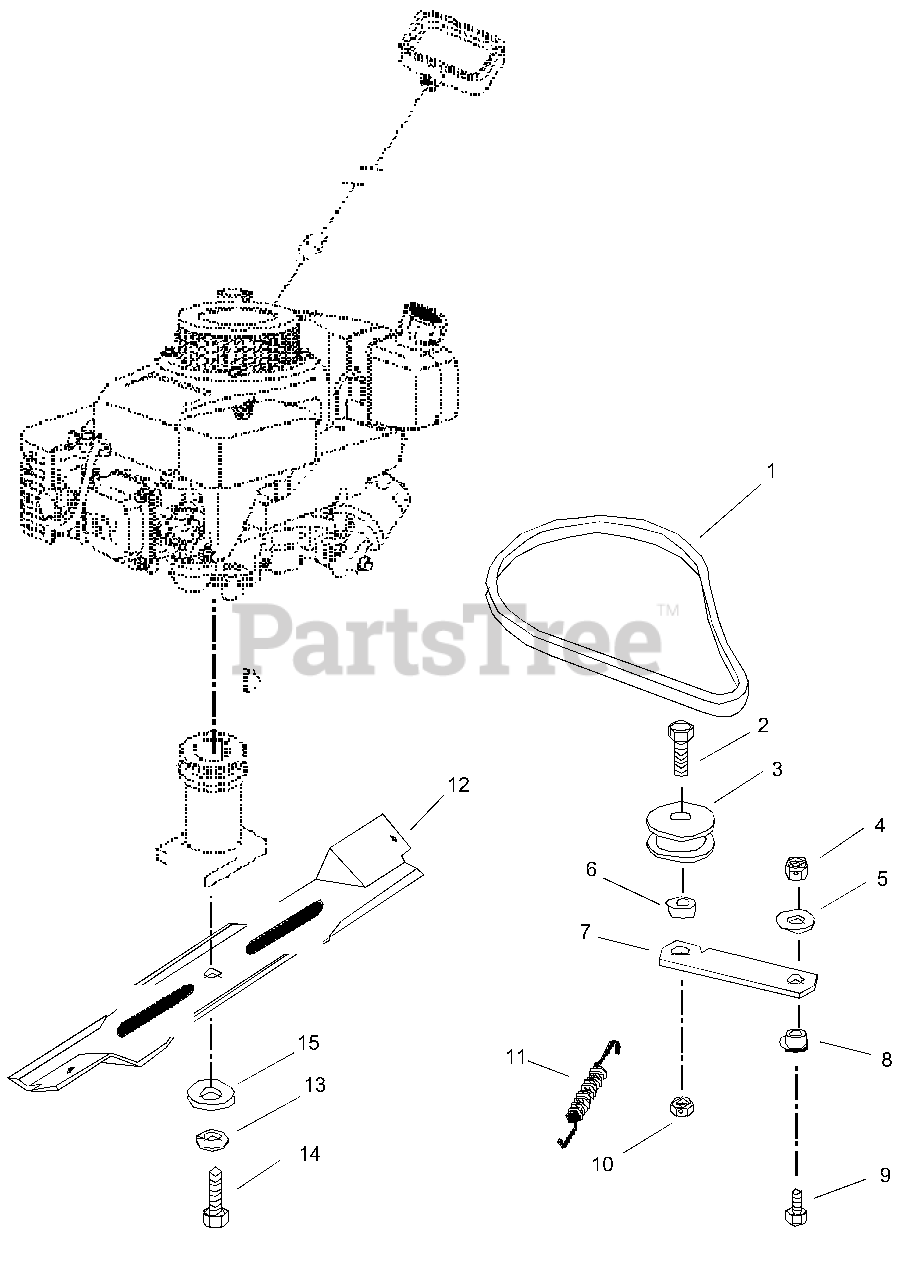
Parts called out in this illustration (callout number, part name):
1	V-BELT, 3L-COGGED
2	@BLT-HEX .44-14X1.25 GR5 YWZC
3	IDLER-FLAT 1.75 X .47
4	@NUT-LK-CTR .31-18 YWZC
5	WSHR-FL-STL .323X.625X.062 YWZ
6	SPACER .52 X .45 X .34
7	IDLER ARM
8	BSHG-FLG .325X.501X.250X1.120
9	@BLT-HEX .31-18X.75 GR5 YWZC
10	@NUT-LK-CTR .44-14 YWZC
11	SG-TENS .043X.44X3.31 WLD 5.8
12	BLADE LM 21 IN
12	21IN MULCHING BLADE
13	@WSHR-LK .38X.094 REG YWZC
14	BLT-HEX .38-24X2.0 YWZC
15	WSHR-FL-STL .390X1.5X.125 YWZC
